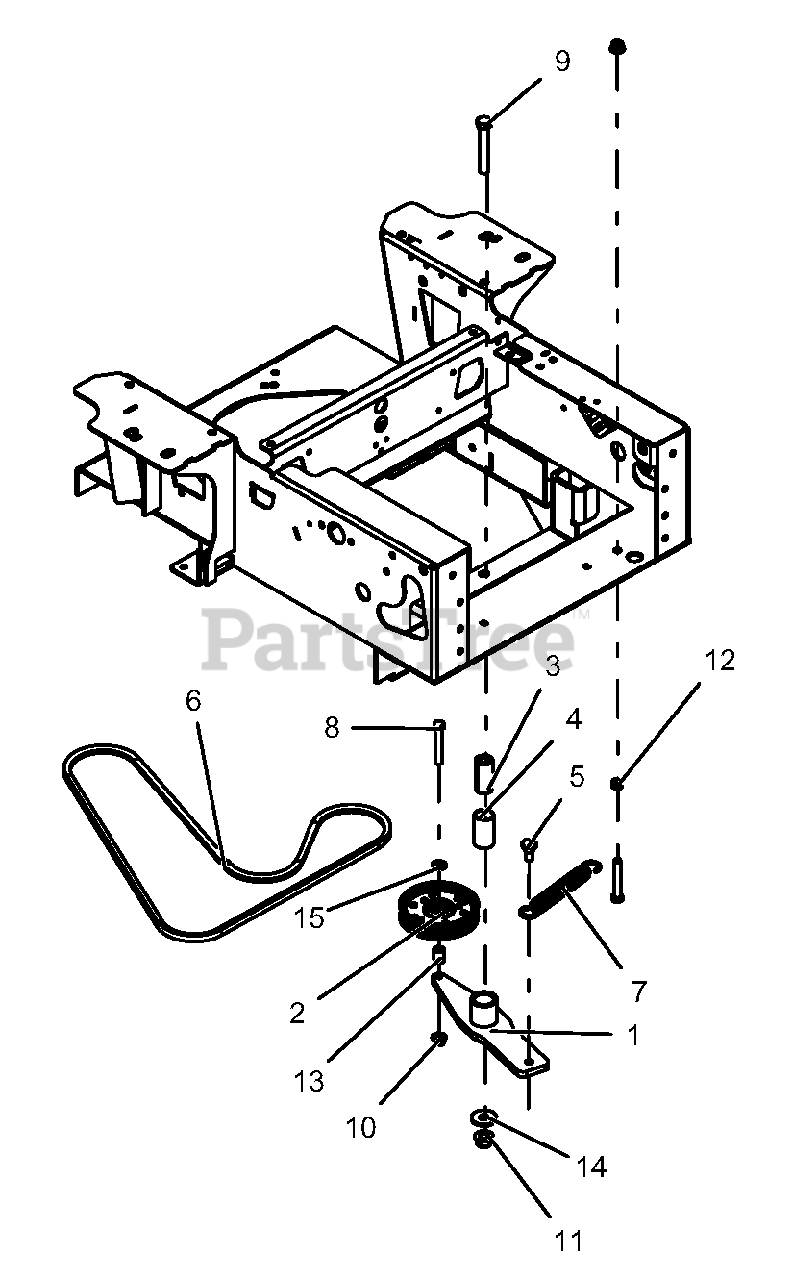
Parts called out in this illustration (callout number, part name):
1	WLDMT, HYDRO DRIVE IDLER ARM - BLK
2	ASM, IDLER 4"
3	BSHG, SPCR .502X.997X2.03
4	BSHG, 1.00X1.125X1.937
5	BLT, SHLDR EP .38-16X.30 HEX YZ
6	BELT, V-A-COGGED
7	SPRG, EXTENSION
8	BLT-HEX .38-16X2.50 GR5 YWZC
9	BLT-HEX .50-13X3.25 GR5 YWZC
10	NUT-LK-NYL-FLG .38-16 YWZC
11	NUT-LK-NYL-FLG .50-13 YWZC
12	NUT-HEX .38-16 YWZC
13	BSHG-SLV .407X.625X.750
14	WSHR-FL-STL .511X1.441x.125 YWZC
15	WSHR-FL-STL .406X.812X.065 YWZ
